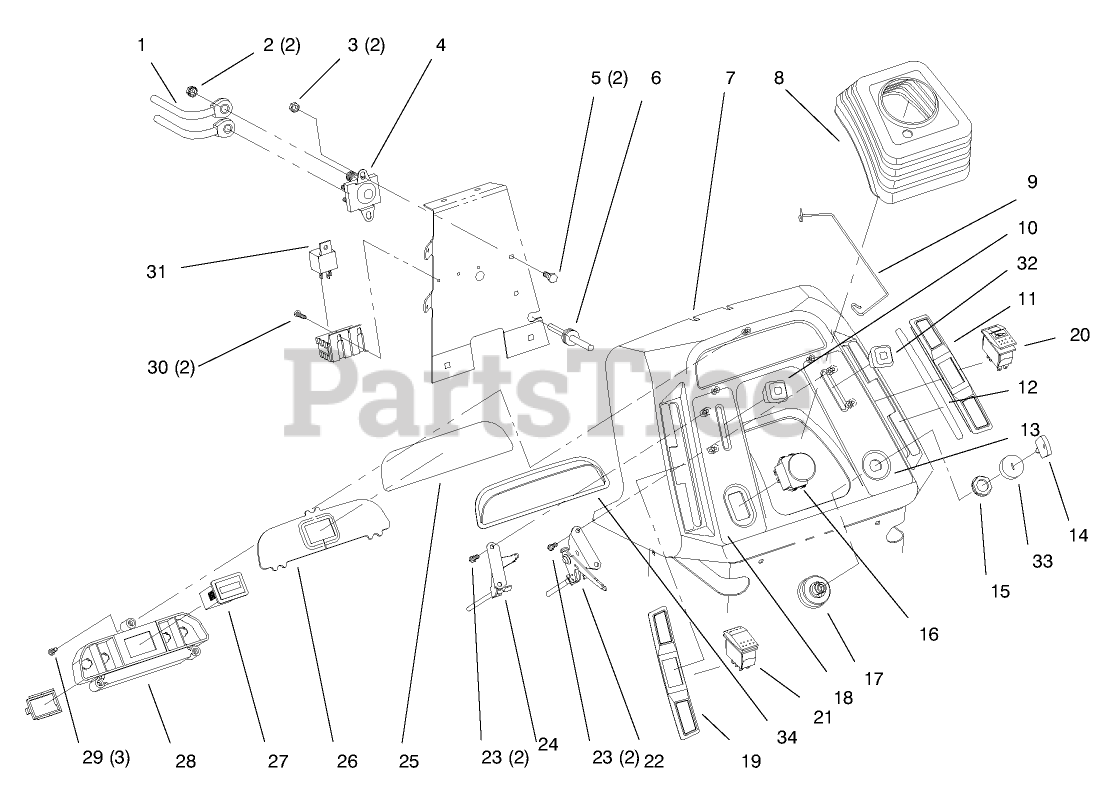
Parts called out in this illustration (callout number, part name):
1	WIRE-21 INCH
2	NUT-KEPS
3	NUT-LOCK, NI
5	SCREW-HH
6	GROMMET-RUBBER
8	BOOT-STEERING
9	CLIP-BOOT
12	DECAL - SHIFT
13	DECAL-THROTTLE, IGNITION
14	KEY-IGNITION
16	SWITCH-PTO,ON-ON-NONE
17	SWITCH-IGNITION
18	DECAL-PTO / CHOKE
19	COVER-SLOT, LH
22	CONTROL-THROTTLE
24	CONTROL-CHOKE
26	LENS-DASH
27	HOURMETER
28	HOUSING-LIGHT, INDICATOR
29	SCREW
30	SCREW-PPHTF
31	RELAY
